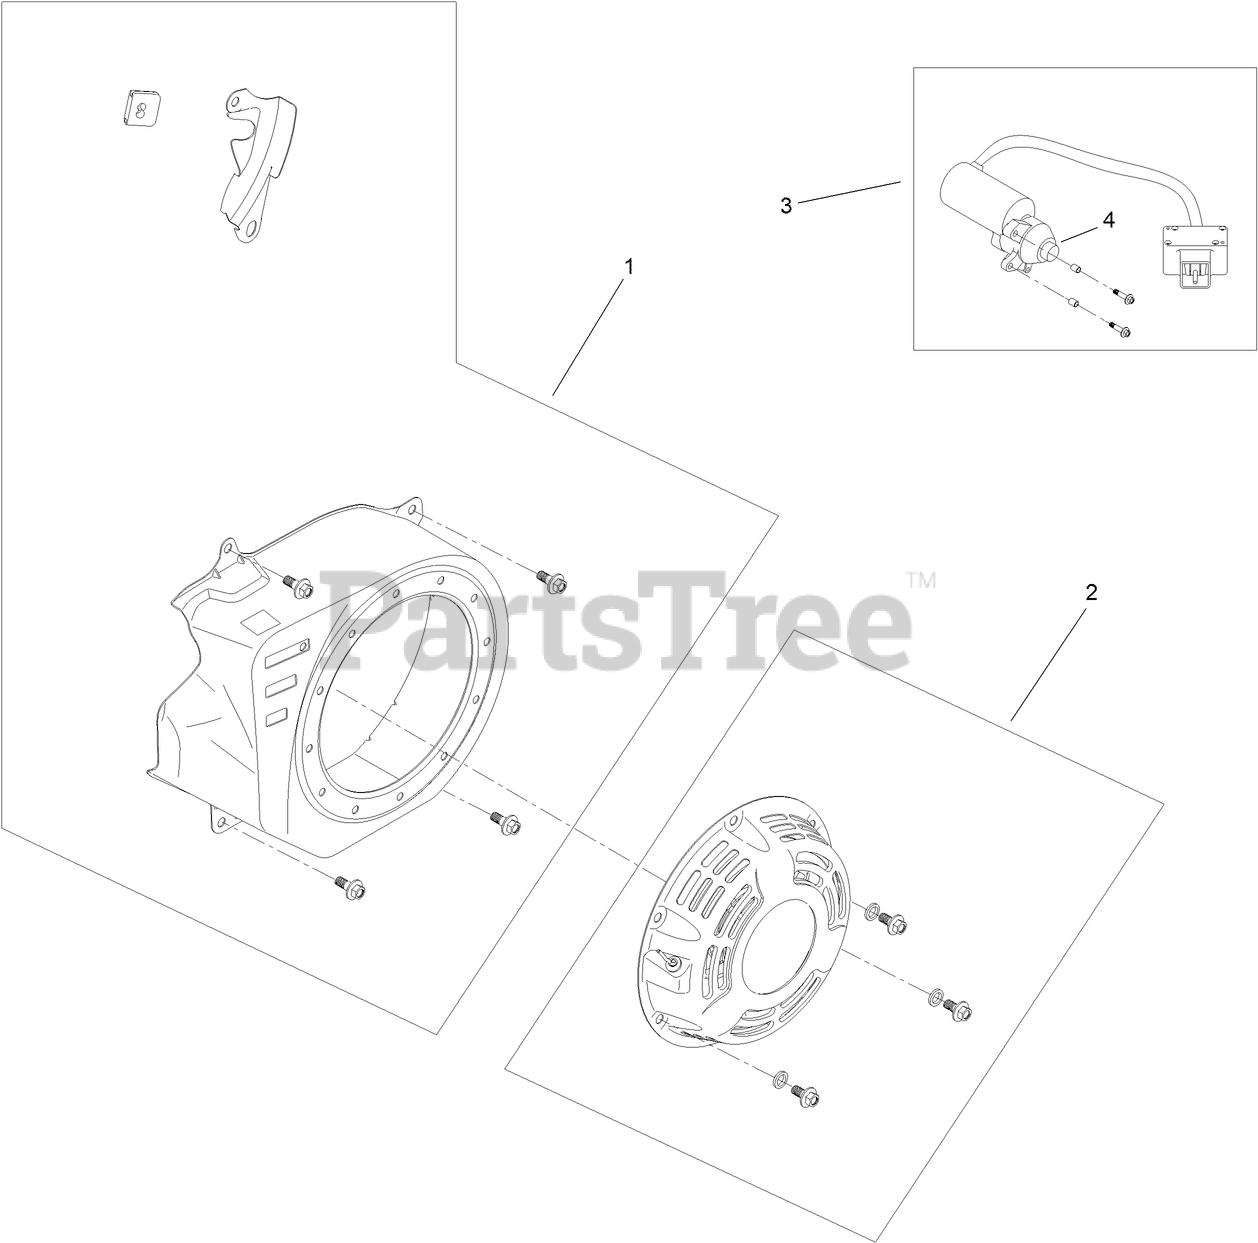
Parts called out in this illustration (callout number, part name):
1	BLOWER SHROUD KIT
2	RECOIL KIT
3	ELECTRIC STARTER KIT
